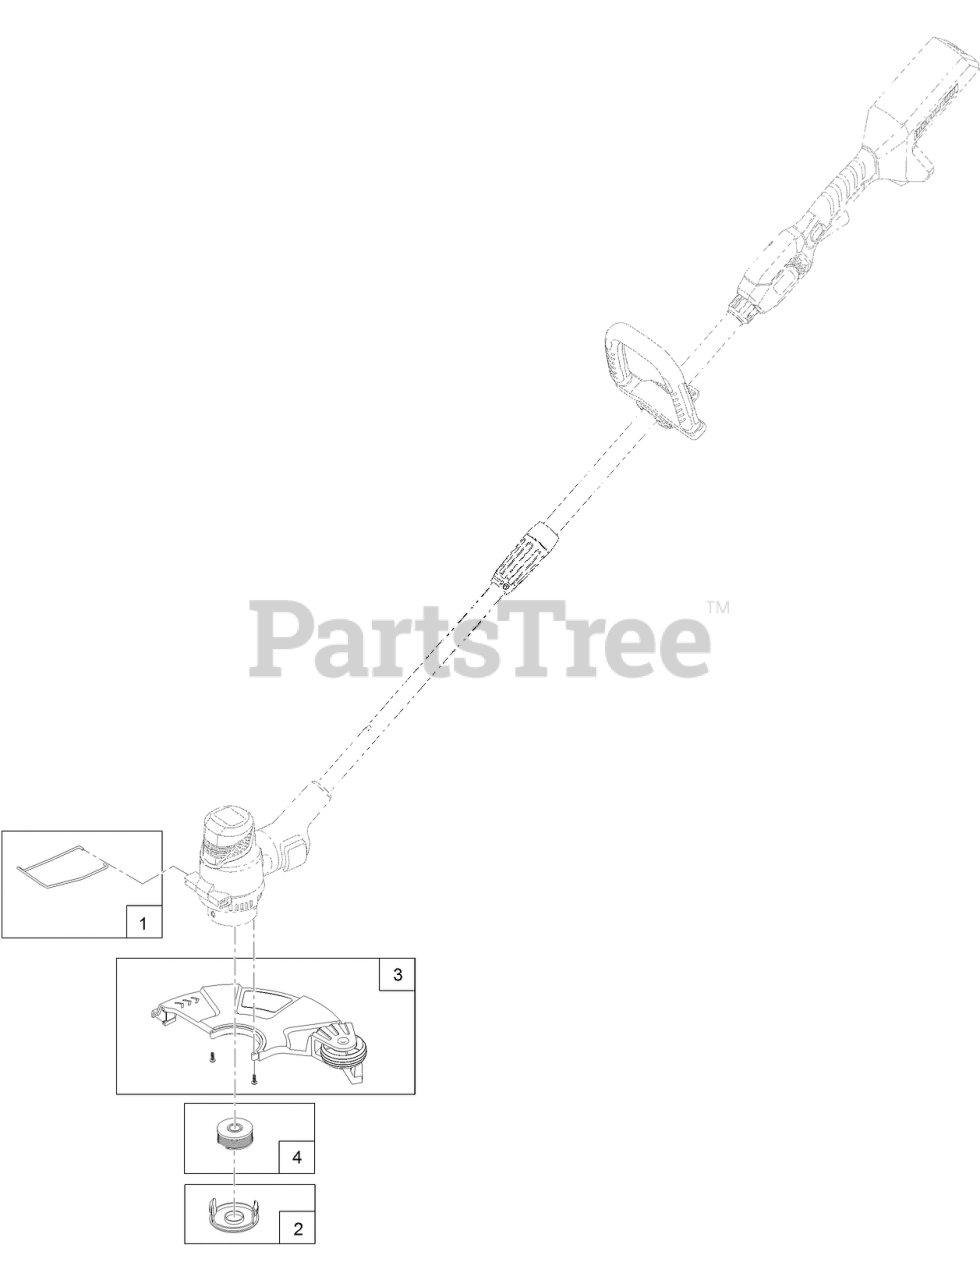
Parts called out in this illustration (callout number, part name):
1	CLIP-WIRE, GUIDE
2	CAP-RETAINER, SPOOL
3	GRASS SHIELD ASM
4	SINGLE LINE SPOOLS (3-PACK)
